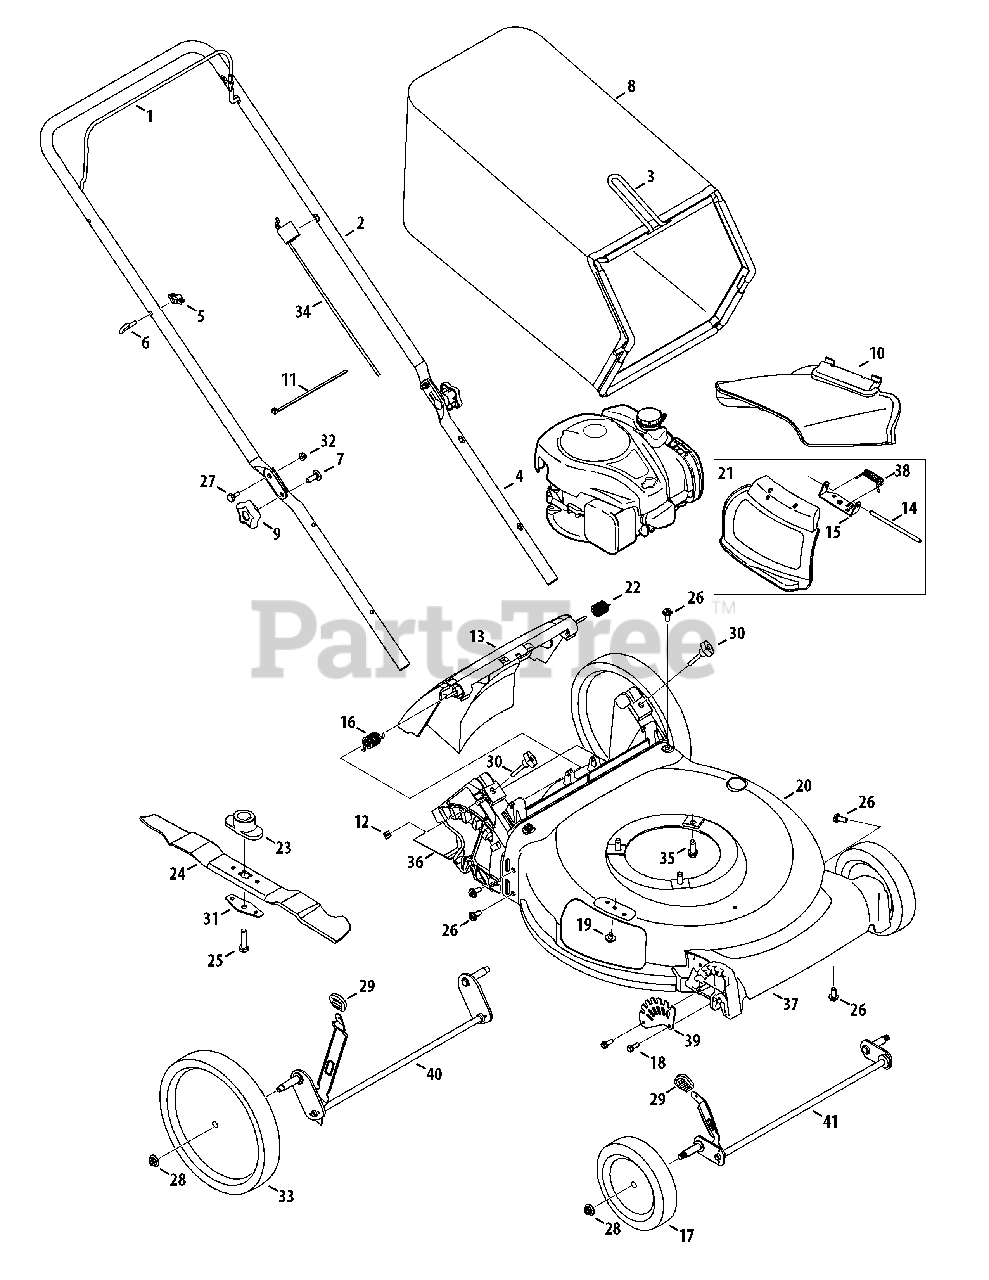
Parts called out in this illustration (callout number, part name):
1	Blade Control
2	Upper Handle
3	Grass Catcher Frame
4	Lower Handle
5	Wing Nut
6	Rope Guide
7	Carriage Screw, 5/16-18
8	Grass Bag
9	Hand Knob
10	Side Chute
11	Cable Tie
12	Nut, Sq., 1/4-20
13	Rear Discharge Door Assembly
14	Hinge Pin
15	Chute Deflector Bracket
16	Torsion Spring - RH
17	Wheel, 7" x 1.8"
18	Screw, 1/4-15 x .750
19	Screw, 1/4-20 x .500
20	Deck - 21"
21	Hinged Mulch Plug Assembly
22	Torsion Spring - LH
23	Blade Adapter
24	Mulching Blade
25	Screw , 3/8-24 x 1.50
26	Screw, 5/16-14 x .750
27	Sldr. Screw, .375 x .126 x 1/4-20
28	Flange Lock Nut, 3/8-16
29	Adjustment Lever Knob
30	Wing Nut
31	Blade Bell Support
32	Nut, Flange Lock, 1/4-20
33	Wheel, 11" x 1.75"
34	Control Cable
35	TT Screw, 3/8-16 x 1.0
36	Trail shield
37	Front Cover
38	Torsion Spring
39	Front Height Adjuster Plate
40	Rear Axle Assembly
41	Front Axle Assembly
